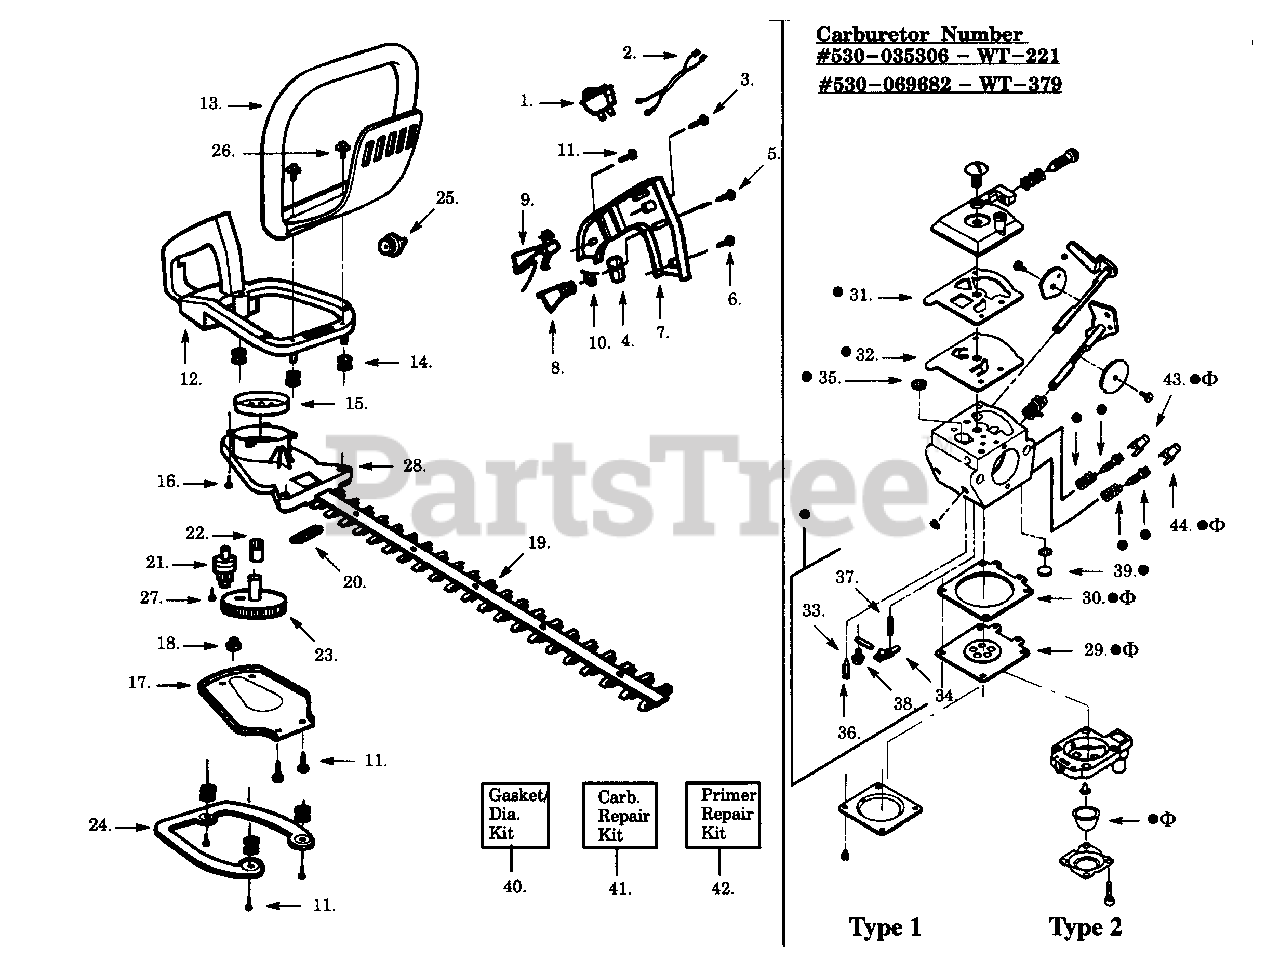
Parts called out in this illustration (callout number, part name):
1	Ignition Switch
2	Lead Wire Ass'y.
3	Screw-Handle Cov.
4	Trigger Lever
5	Screw-Handle Cov.
6	Screw-Handle Cov.
7	Handle Cover
8	Throttle Trigger
9	Throttle Lockout
10	Trigger Spring
11	Screw-Handle Cov.
12	Rear Handle/Tank Ass'y.
13	Front Handle
14	Isolator Spring
15	Clutch Drum
17	Gear Box Plate
18	Bushing Blade
19	Blade Ass'y., 17"
19	Blade Ass'y., 22"
20	Blade Seal
21	Pinion Ass'y.
22	Drive Gear Bearings
23	Drive Gear Kit
24	Isolator Plate
25	Fuel Cap Ass'y.
26	Screw-Front Handle
27	Screw-Gear
28	Gear Box Ass'y. (Incl. 21, 22 & 27)
29	Metering Diaphragm Type 1 Only
30	Metering Diaphragm Gasket Type 1 Only
31	Pump Gasket Type 1 Only
32	Pump Diaphragm Type 1 Only
33	Metering Pin Type 1 Only
34	Metering Lever Type 1 Only
35	Fuel Inlet Screen Type 1 Only
36	Inlet Needle Valve Type 1 Only
37	Metering Lever Spring Type 1 Only
38	Metering Lever Pin Screw Type 1 Only
39	Welch Plug Type 1 Only
40	Gasket/Diaphragm Kit (Incl. 29-32) Type 1
41	Carb. Repair Kit-, (WT-221) (Incl. 33-38,& 40) Type 1
41	Carb. Repair Kit-, (WT-379) ( . Indicates Contents) Type 2
43	Limiter Cap-Low Type 2 Only
44	Limiter Cap-High Type 2 Only
